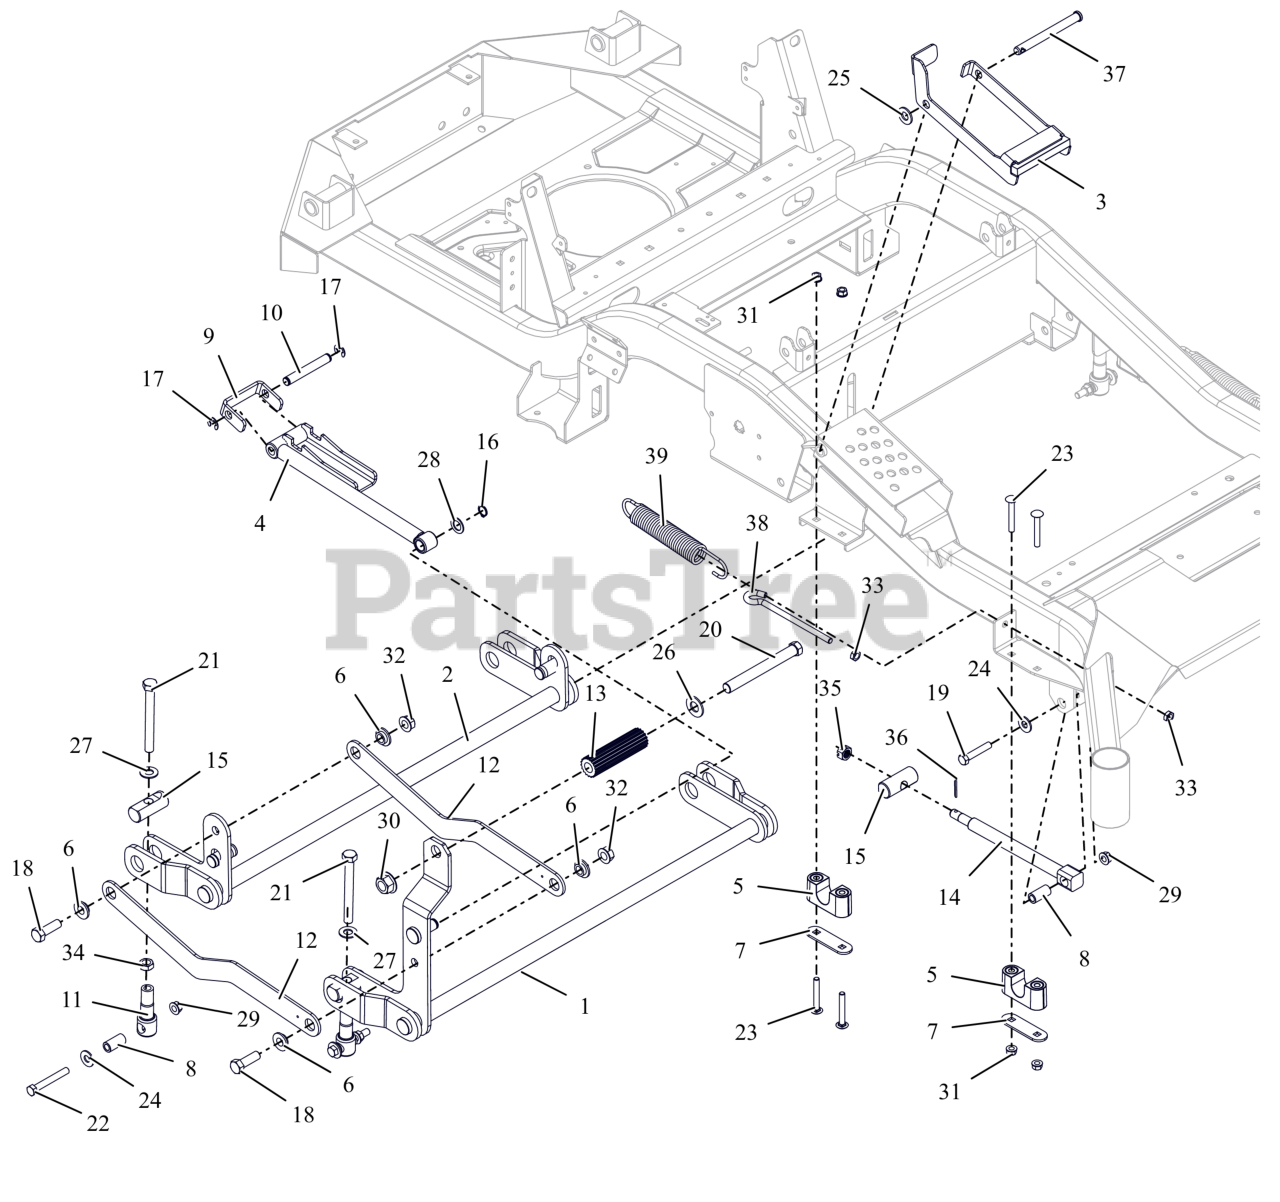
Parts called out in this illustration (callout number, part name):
1	WLDMT, FRONT DECK LIFT PIVOT
2	WLDMT, REAR DECK LIFT PIVOT
3	BRKT, HOC TRANSFER LOCK
4	WLDMT, HOC ARM
5	ASM-BUSHING, DECK LIFT
6	BSHG-FLG .515X.750X.395X1.120
7	PLATE, BEARING SUPPORT
8	SPACER, DECK LEVELING
9	BRKT, HOC LINE
10	ROD, HOC PIVOT
11	LINK, DECK LIFT FORMED
12	LINK, DECK LIFT
13	ROD, FOOT PEDAL (BLACK)
14	DRAG,LINK-HD
15	PIN, DECK LIFT
16	RG-RTNG-EXT .625X.050
17	RG-RTNG-EXT .500X.042 (E)
18	BLT,HEX .50-13X1.50 G5 ZCC
19	BLT,HEX .38-16X2.00 G5 ZCC
20	BLT, HEX .62-11X5.50 G5 FBP
21	BLT, HEX .50-13X4.50F G8 ZCC
22	BLT, HEX .38-16X2.75 G8 ZCC
23	BLT, RHSSN.31-18X2.25 G5 ZCC
24	WSHR,FLT .438X1.00X.083 ZCC
25	WSHR,FLT .531X1.062X.095 ZCC
26	WSHRFLT 5/8SAE CARBHARD FBP
27	WSHR, FLT .557X1.040X.102 ZCC
28	WSHR, FLT .630X1.005X.062 ZCC
29	NUT-LK-TOP-FLG .38-16 ZC120
30	NUT,FLG-TOP LK .625-11 FBP
31	NUT,LK-CTR-FLG .31-18 GF ZCC
32	NUT-LK-TOP-FLG .500-13 GF ZCC
33	NUT-JAM .375-16 G2 ZCC
34	NUT-JAM .500-13 G2 ZCC
35	NUT-SL .50-13
36	PIN,CTR.12X1.25EXTPRSQCT ZC120
37	PIN-SLIC .50X4.97X4.55 -ZCC
38	BOLT,.38-16 X 5.25-.62 DIA EYE
39	SG-TENS .162X1.25X8.25 WLD 25
